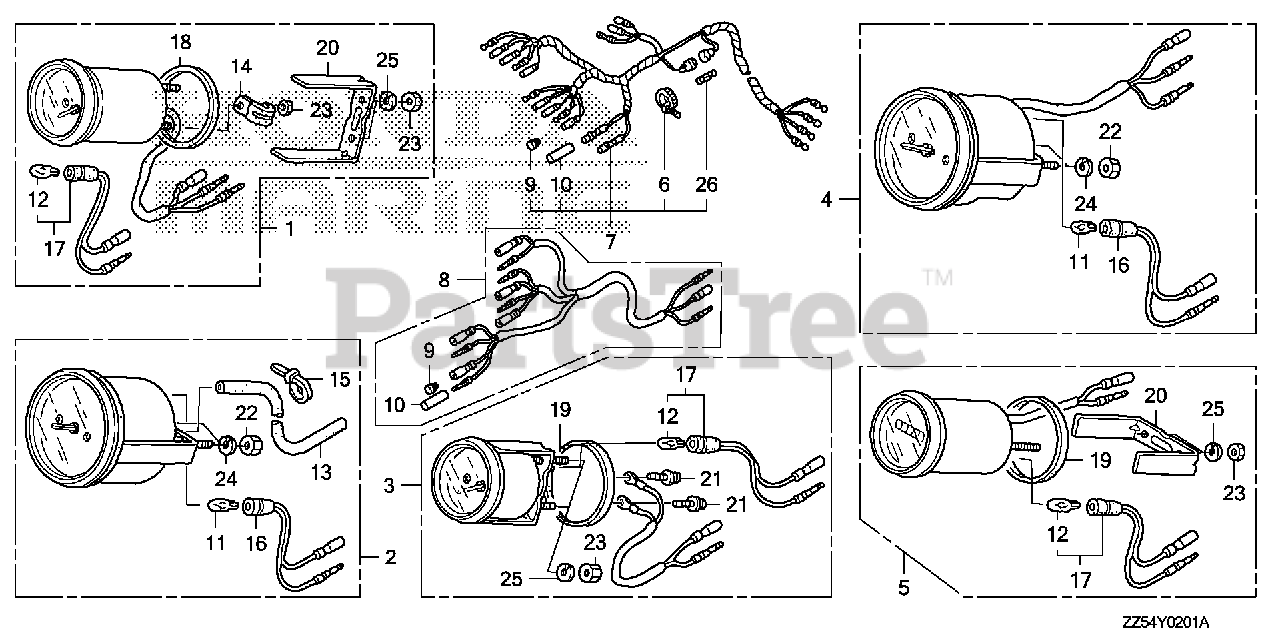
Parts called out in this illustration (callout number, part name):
4	METER KIT, TACHO
4	METER KIT, TACHO (B)
6	BAND B1, WIRE
7	HARNESS ASSY., METER (A)
9	PLUG, CONNECTOR (INNER)
10	PLUG, CONNECTOR (OUTER)
11	BULB, WEDGE BASE (T10) (12V 1.7W) (STANLEY)
16	SOCKET
22	NUT, HEX. (5MM)
24	WASHER, SPRING (5MM)
26	FUSE A (10A)
